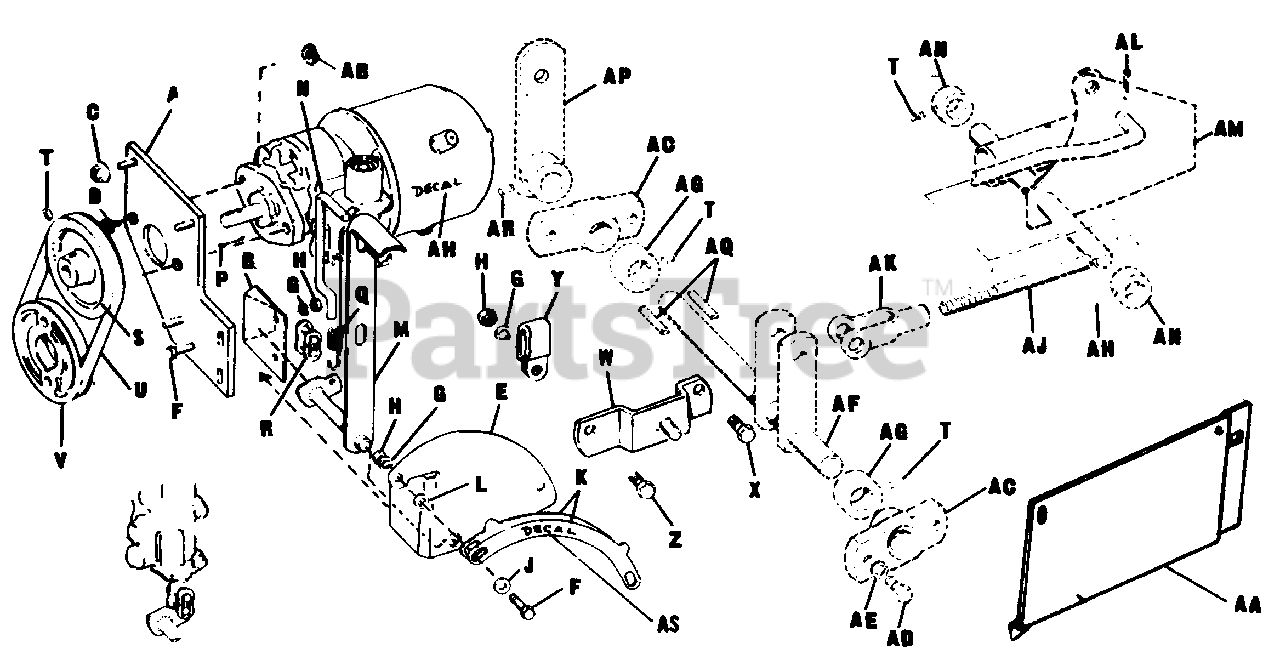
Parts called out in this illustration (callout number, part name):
A	Pump Support Assembly
B	Angle Bracket
C	Hex. Nut, Whiz Lock, 5/16"-18
D	Machine Screw Flat Hd. 3/8-16 x 1-1/4" lg.
F	Hex. Cap Screw, 1/4"-20 x 3/4"
G	Lock Washer, 1/4"
H	Full Hex. Nut, 1/4"-20
J	Plain Washer, 1/4"
K	Stop Plate
M	Lever Assembly
N	Latch Rod
P	Cotter Pin, 3/32" x 5/8"
R	Connecting Link
S	Pump Pulley
T	Set Screw, 5/16"-18 x 5/16"
V	Drive Pulley
W	Pivot Bar Assembly
X	Hex. Cap Screw, 5/16"-18 x 1"
Y	Hose Clamp
Z	Hex Cap Screw, 1/4"-20 x 1"
AA	Panel, Side L.H.
AB	Nut-Whiz Lock 3/8"-16
AC	Lift Lever Bearing
AD	Hex. Cap Screw, 3/8"-16 x 7/8"
AE	Lock Washer, 3/8"
AF	Lift Shaft Assembly
AG	Set Collar
AJ	Lift Rod (For 10) (For 12 164122)
AK	Adj. Yoke End
AL	Cotter Pin, 1/8" Dia. x 1"
AM	Tiller Lift Assembly
AN	Set Collar
AP	Front Lift Lever Assembly
AR	Set Screw, 5/16"-18 x 1/4"
